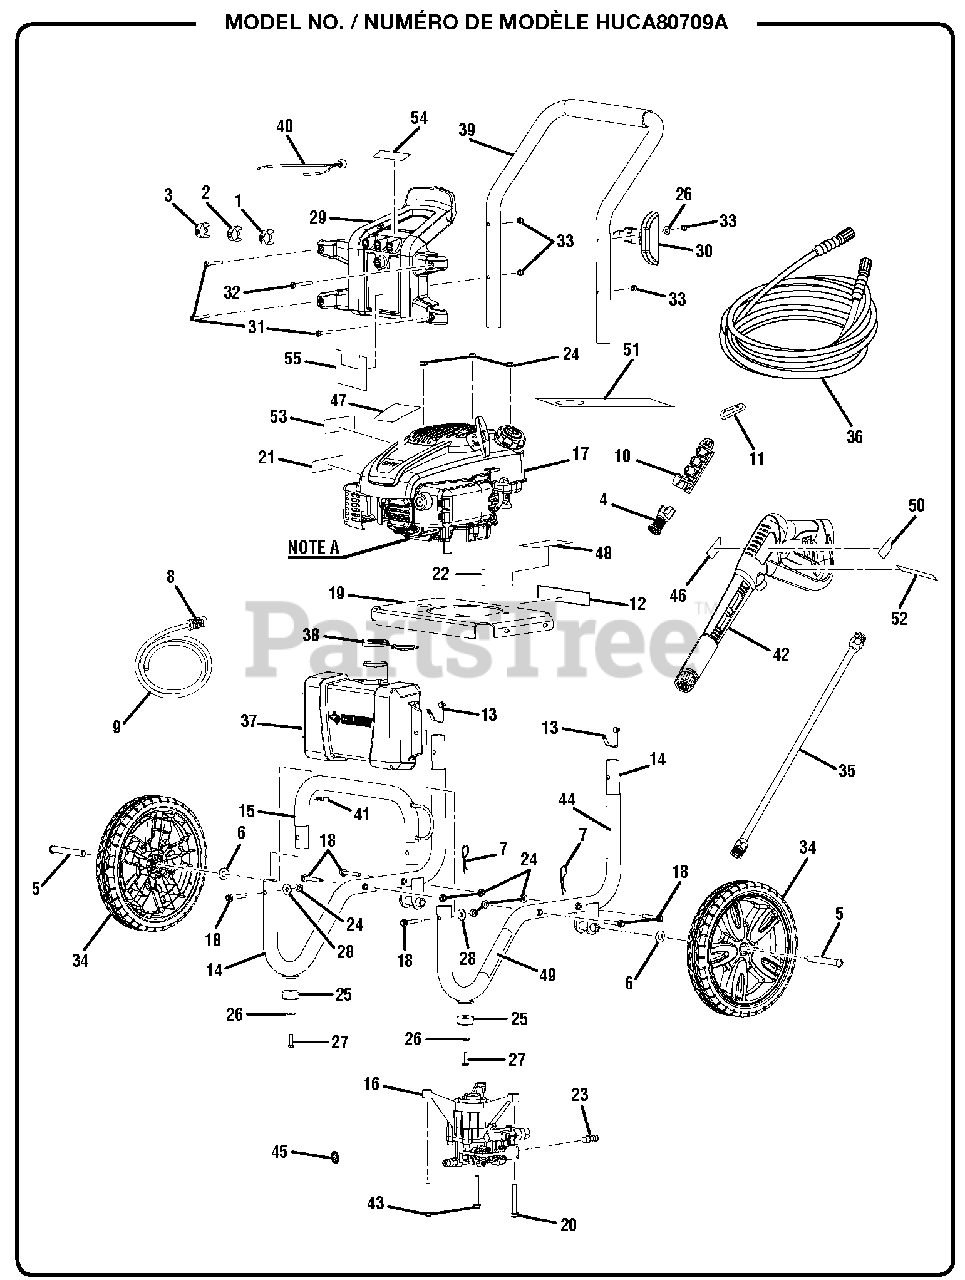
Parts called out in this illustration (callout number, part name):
1	0deg Nozzle
2	25deg Nozzle
3	40deg Nozzle
4	Soap Blaster Nozzle
5	Axle
6	Washer (1/2 in.)
7	Hitch Pin
9	Injection Hose
10	Nozzle Holder
11	Spring Clip
12	Data Label
13	Lock Button w/Spring Clip
14	Main Frame Assembly
15	Front Frame
16	Pump
17	Engine (Kohler)
18	Bolt (M8 x 55 mm, Hex Hd.)
19	Engine Plate
20	Screw (3/8-16 x 40 mm)
21	Check Lubricant Label
22	Output Shaft Key
23	Thermal Relief Valve
24	Lock Nut (M8 x 1-1/4 in.)
26	Washer (1/4 in.)
27	Bolt (1/4-20 x 1 in., Hex Hd.)
28	Washer (5/16 in.)
29	Hose and Nozzle Holder
30	Wand Holder
31	Screw (1/4-20 x 1.85 in., Torx)
32	Screw (1/4-20 x 2.27 in., Torx)
33	Lock Nut (1/4-20)
34	Wheel (12 in. x 2 in.)
35	Spray Wand
36	High Pressure Hose
37	Soap Tank
38	Soap Tank Cap
39	Handle Assembly
40	Bungee Cord and Bead Assembly
41	Injection Hose Holder
42	Trigger Handle Assembly
43	Bolt (M8 x 60 mm, Flange Hex Hd.)
44	Engine Quick Start Label
45	Filter Screen
46	Trigger Handle Warning
47	Engine Logo Label
48	Warning Label
49	Pump Quick Start Label
50	Trigger Handle Logo
51	Engine Oil Fill Hang
52	Wand Rating Label
53	Hot Surface Label
54	Nozzle Label
55	Performance Label
